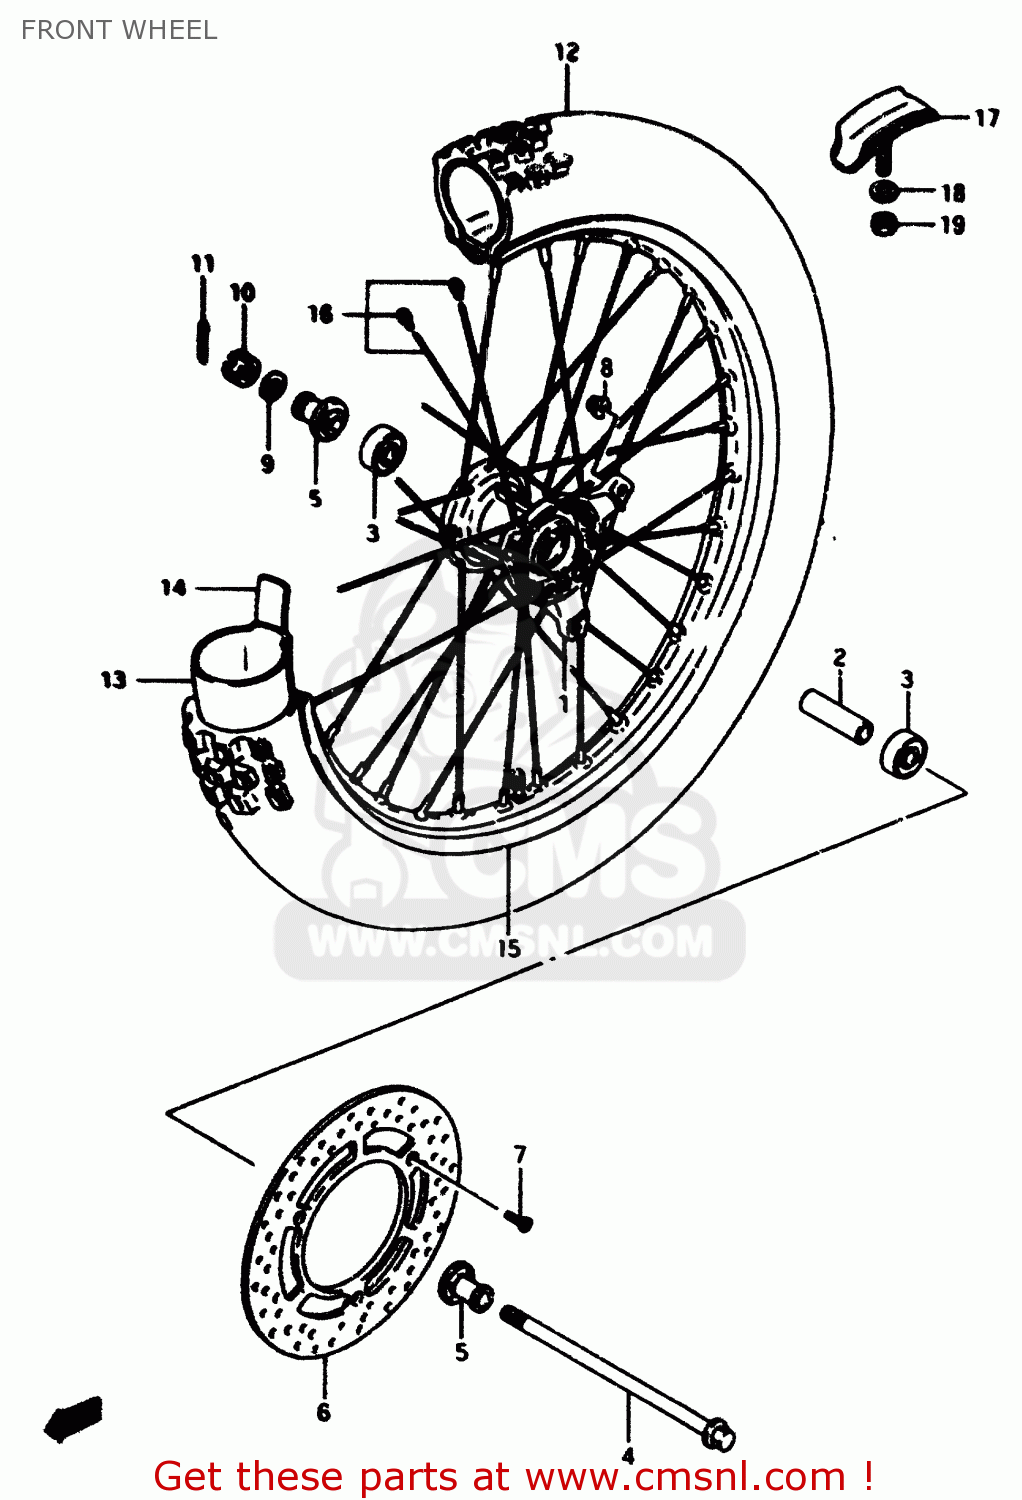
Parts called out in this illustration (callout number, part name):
1	HUB,FR WHEEL
2	SPACER,FR HUB BEARING
3	BEARING (12X32X10)
4	AXLE,FR
5	SPACER,FR AXLE
6	DISC,FRONT BRAKE
7	SCREW(6X22)
8	NUT
9	WASHER
10	NUT,M12X1.25X1
11	PIN 20X20
12	TIRE,FRONT 70/100-17
13	TUBE ASSEMBLY,WHEEL,INNER
14	PROTECTOR,WHEEL,INNER
15	RIM,FR WHEEL(1.40X17)
16	SPOKE SET,FR WHEEL
17	STOPPER,BEAD
18	WASHER
19	NUT
